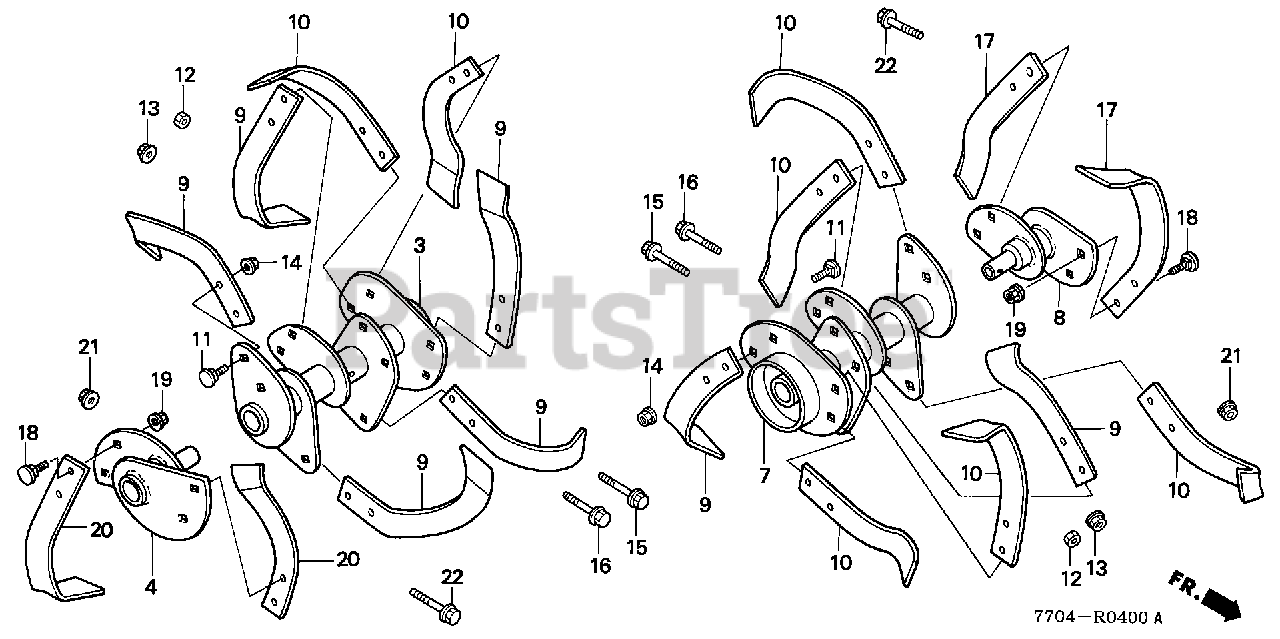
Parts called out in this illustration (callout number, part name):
3	SHAFT, R. ROTARY PIPE *NH1* (BLACK)
4	SHAFT, R. ROTARY PIPE EXTENSION *NH1* (BLACK)
7	SHAFT, L. ROTARY PIPE *NH1* (BLACK)
8	SHAFT, L. ROTARY PIPE EXTENSION *NH1* (BLACK)
9	TINE, R. ROTARY *NH1* (BLACK)
10	TINE, L. ROTARY *NH1* (BLACK)
11	BOLT, SPECIAL (10X22)
12	NUT, SELF-LOCK (8MM)
13	NUT, SELF-LOCK (10MM)
14	NUT, FLANGE (10MM)
15	BOLT, FLANGE (8X50)
16	BOLT, FLANGE (10X50)
17	TINE, L. ROTARY *NH1* (BLACK)
18	BOLT, SPECIAL (10X22)
19	NUT, FLANGE (10MM)
20	TINE, R. ROTARY *NH1* (BLACK)
21	NUT, SELF-LOCK (10MM)
22	BOLT, FLANGE (10X50)
